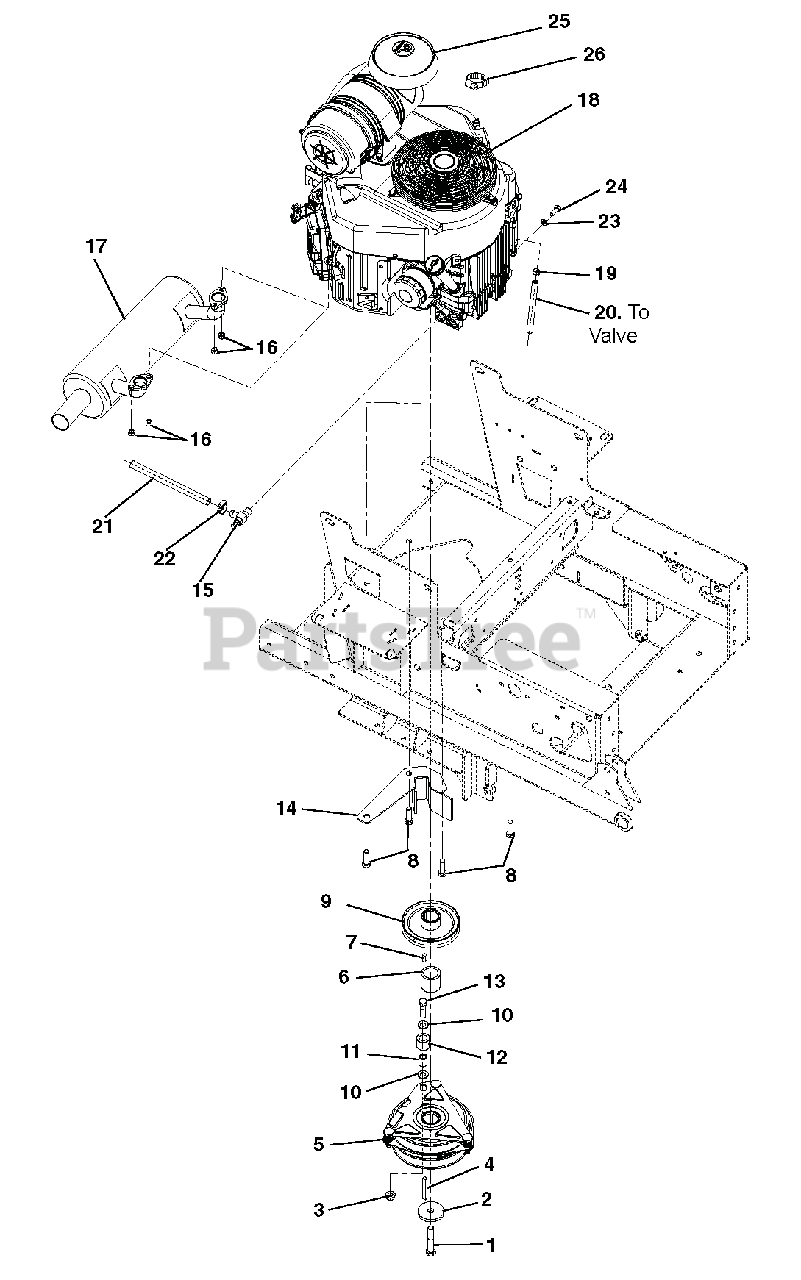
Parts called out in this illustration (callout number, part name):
1	BLT-HEX .44-20X2.50 G5 YZ EP80
2	WSHR-FL-STL .469X2.00X.25 YWZC
3	@NUT-LK-TOP-FLG .38-16 YWZC
4	KEY .25X.25X2.25
5	CLUTCH, OGURA GT2.5-FE02
6	SPACER, 1.125 X 1.75 X 1.40
7	KEY-SQ .25X.625X.25 SAE 8630
8	BLT-HEX.38-16X1.25FTHG5 EP30YZ
9	SHEAVE, 4.831 X 1.127 ENGINE
10	@WSHR-FL-STL.406X.812X.065 YWZ
11	BUSH.,S.407X.625X.813 ST
12	BUMPER,RUBBER .62X1.0X.88 LG
13	@BLT-HEX .38-16X1.50 GR5 YWZC
14	100I CLUTCH STOP WMT - BLACK
15	DRAIN, 1/2" OIL
16	NUT-LK-TOP M8-1.25 YWZC
17	MUFFLER, KAWASAKI FX 24/26HP
18	ENGINE, KAWASAKI FX691 (24HP)
19	CLAMP, FUEL LINE
20	HOSE, .25 LOW-PERM BULK GAS
21	TUBE, OIL DRAIN 8" CLEAR VINYL
22	CLAMP,.88 DIA. HOSE
23	@WSHR-LK .31X.078 REG YWZC
24	@BLT-HEX M8-1.25X20 YWZC
25	CAP, KAW 11065-7025
26	CLAMP, HOSE #36 SS 1.813-2.75
